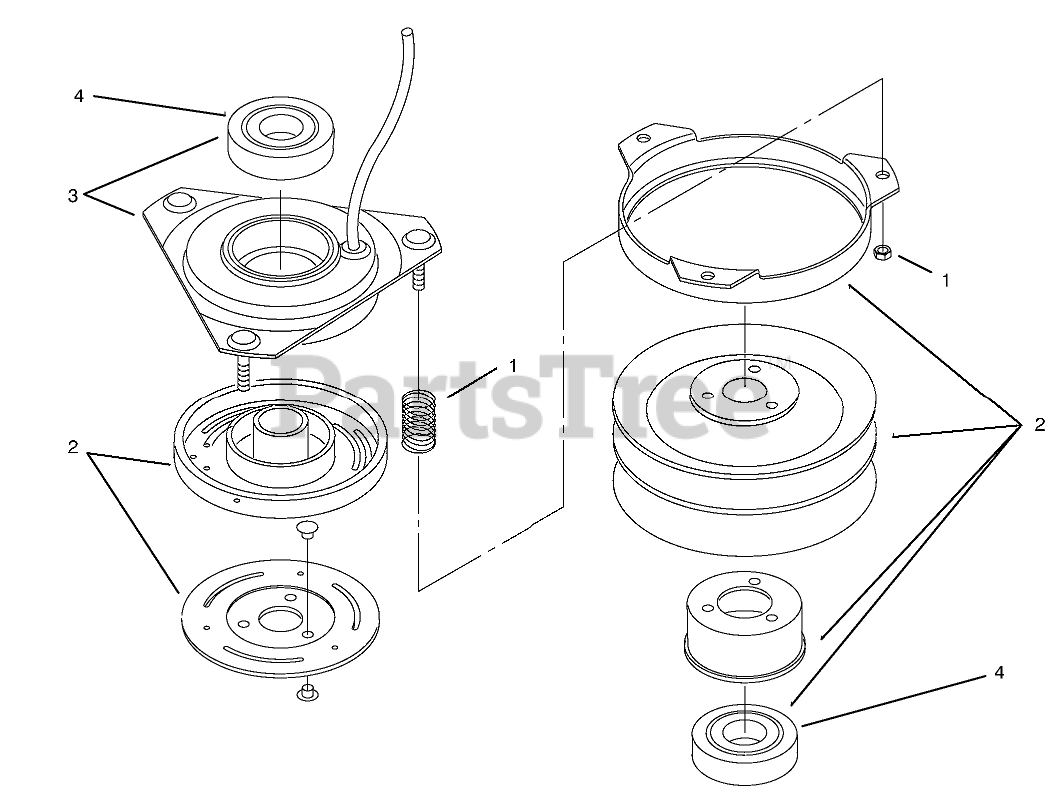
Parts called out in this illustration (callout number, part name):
1	ACCESSORY PKG SRVC PART
2	Rotor ASM w/Bearing (Only On: 72104)
2	Rotor & Armature ASM (Only On: 72085)
3	FIELD ASSY (SRVC PART)
4	BEARING-ELEC CLUTCH
